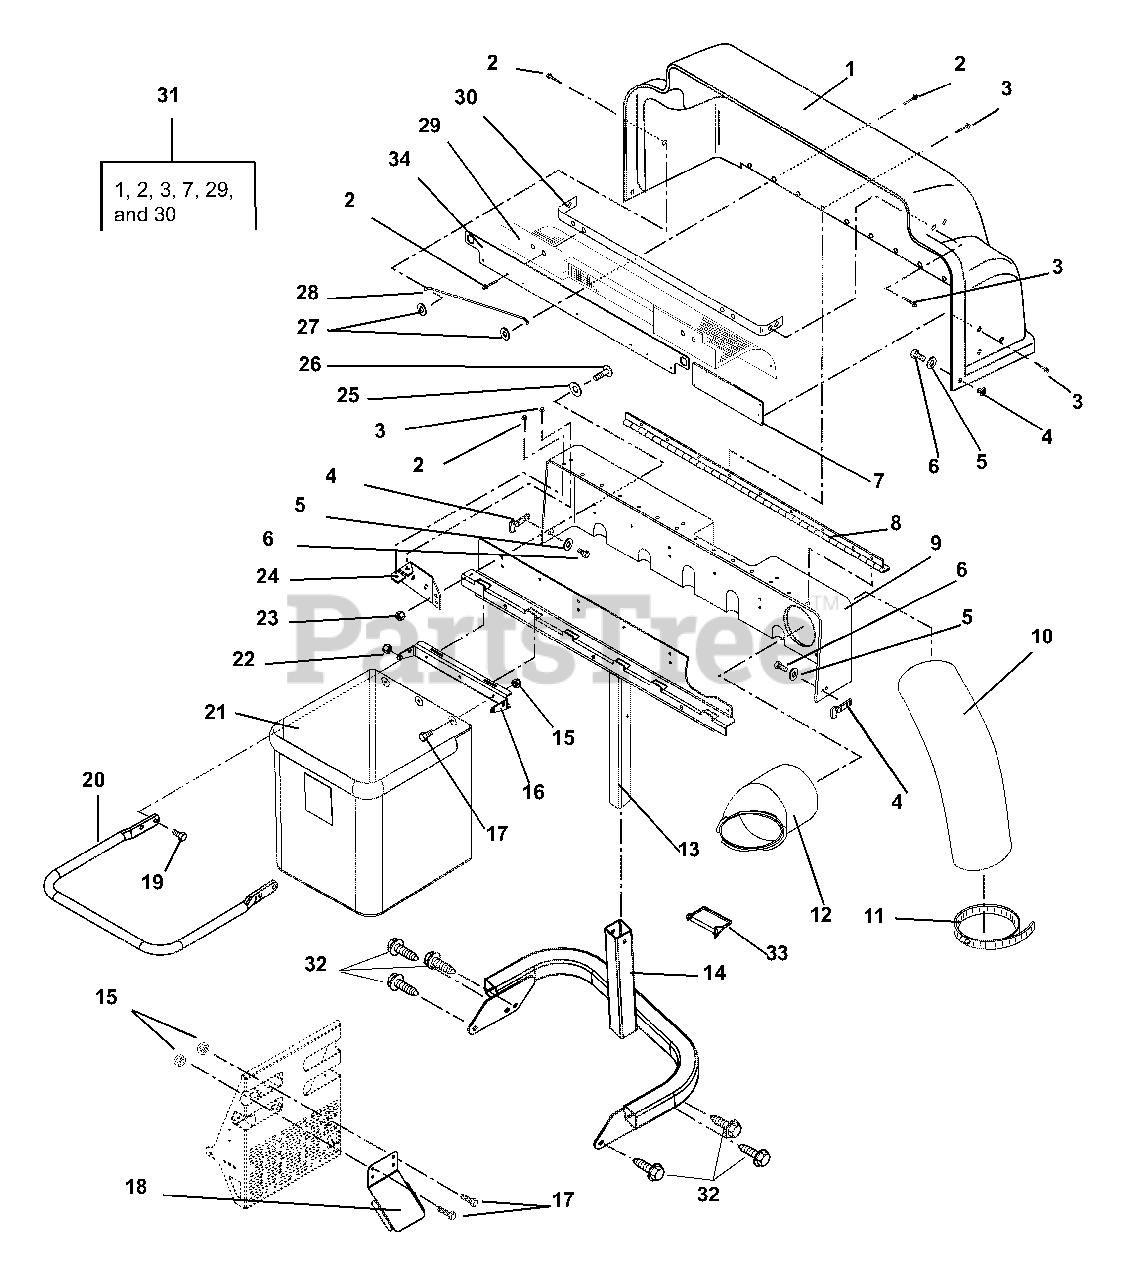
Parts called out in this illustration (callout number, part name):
1	Hinged Cover with Decal
2	Rivet-Pop .187 x .527
2	(Gravely Part Number)
3	Rivet-Pop .187 x .402
4	Latch, Rubber
5	Washer-Flat-Steel .219 x .50 x .049
6	Screw-Machine 10-24 x .50 Hex Washer Head
9	Stationary Cover
9	(Gravely Part Number)
10	Hose 7 x 45
11	Clamp-Hose Worm 2.13/8.62 x.56
11	(Gravely Part Number)
12	Bagger Boot- Upper
12	(Gravely Part Number)
13	Weldment-Bagger Frame
14	Weldment-Bumper
15	Nut-Locking-Center .25-20
16	Weldment, Hanger Frame
17	Bolt-Hex .25-20 x .50 Grade 5
18	Deflector, Exhaust
19	Bolt-Round Head Square Short Neck .31-18 x .75 Grade 5
20	Frame-Bag Support
21	Bag-Mesh Assist Bagger
22	Nut-Spin Lock-Flange .312-18
23	Nut- Locking-Nylon .312-18 Grade 2
24	(Gravely Part Number)
25	Washer-Flat-Steel .38 x .875 x .083
26	Bolt-Hex .31-18 x .75 Grade 5
27	Washer-Flat-Steel .219 x .50 x .049
28	(Gravely Part Number)
30	Screen Mounting Bracket
31	Hinged Cover Assembly
32	Screw-Tapping .38-16 x .75 Hex Washer Head
33	Pin, 3/8 x 2.50 Square Lock
34	Guard, Screen
